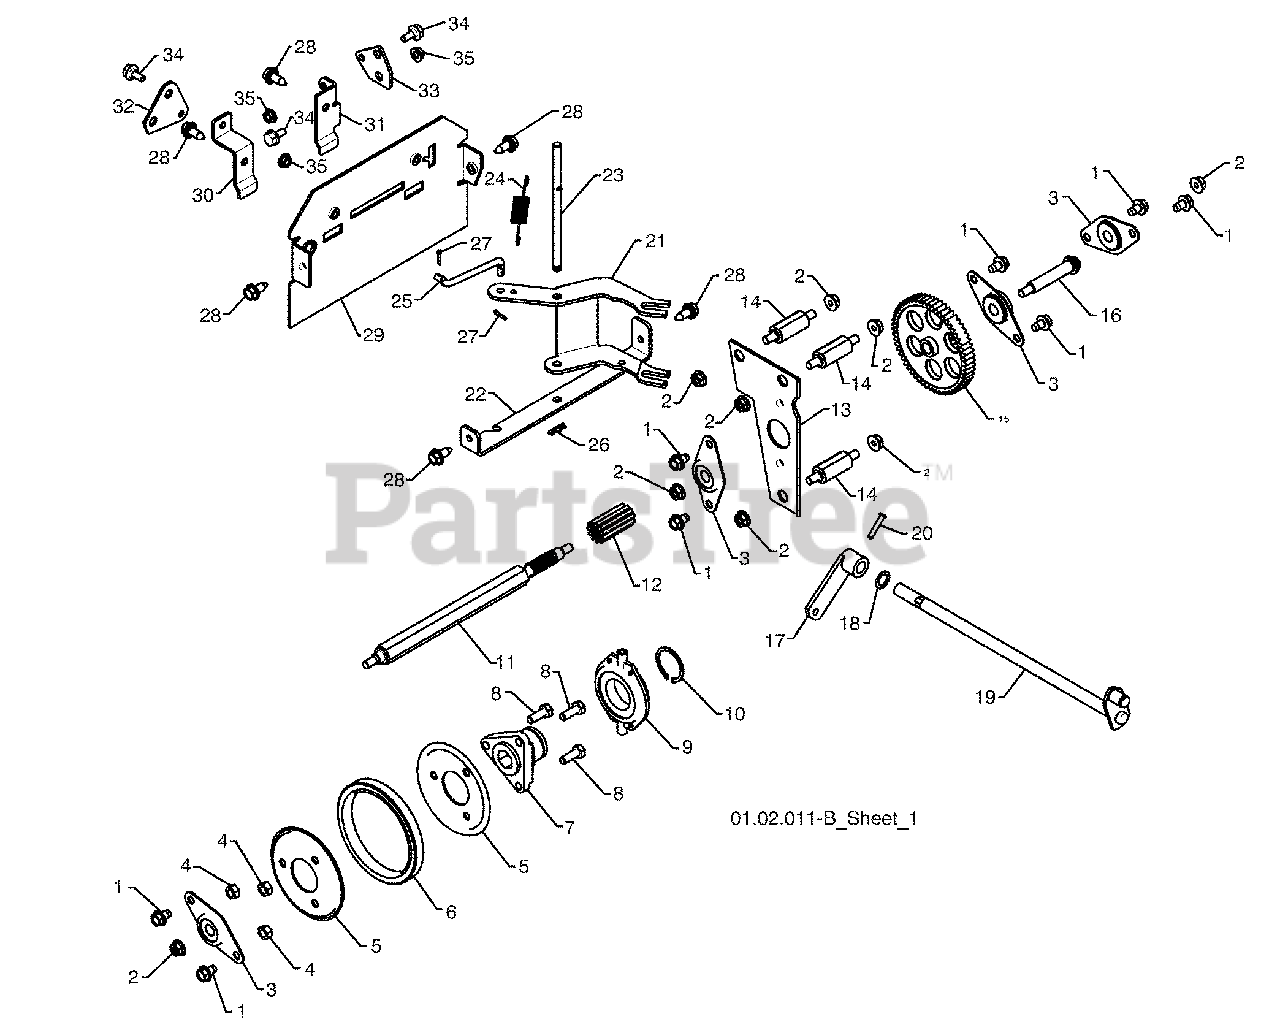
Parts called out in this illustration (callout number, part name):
1	BOLT 5/16-18 X .500
2	NUT 5/16-18
3	FLANGE BEARING
4	NUT 5/16-18
5	RUBBER WHEEL PLATE
6	RUBBER WHEEL RING
7	RUBBER WHEEL HUB
8	BOLT 5/16-18 X .875
9	TRUNNION BEARING ASSEMBLY
10	RETAINER
12	PINION GEAR
13	AUXILIARY PLATE
14	SPACER PLATE
15	INTERMEDIATE GEAR
16	AUXILIARY SHAFT
17	CONTROL ARM
19	CONTROL SHAFT ASSEMBLY
20	CLEVIS PIN
21	SHIFTER LEVER
22	PIVOT BRACKET
25	SHIFTER LINK
28	SCREW 5/16-18 x .750
29	REAR PLATE
30	SHIFTER PLATE BRACKET
31	CLUTCH PLATE BRACKET
32	SHIFTER PLATE
33	CLUTCH PLATE
34	SHOULDER BOLT 3/8 x .25
35	NUT 1/4-20
